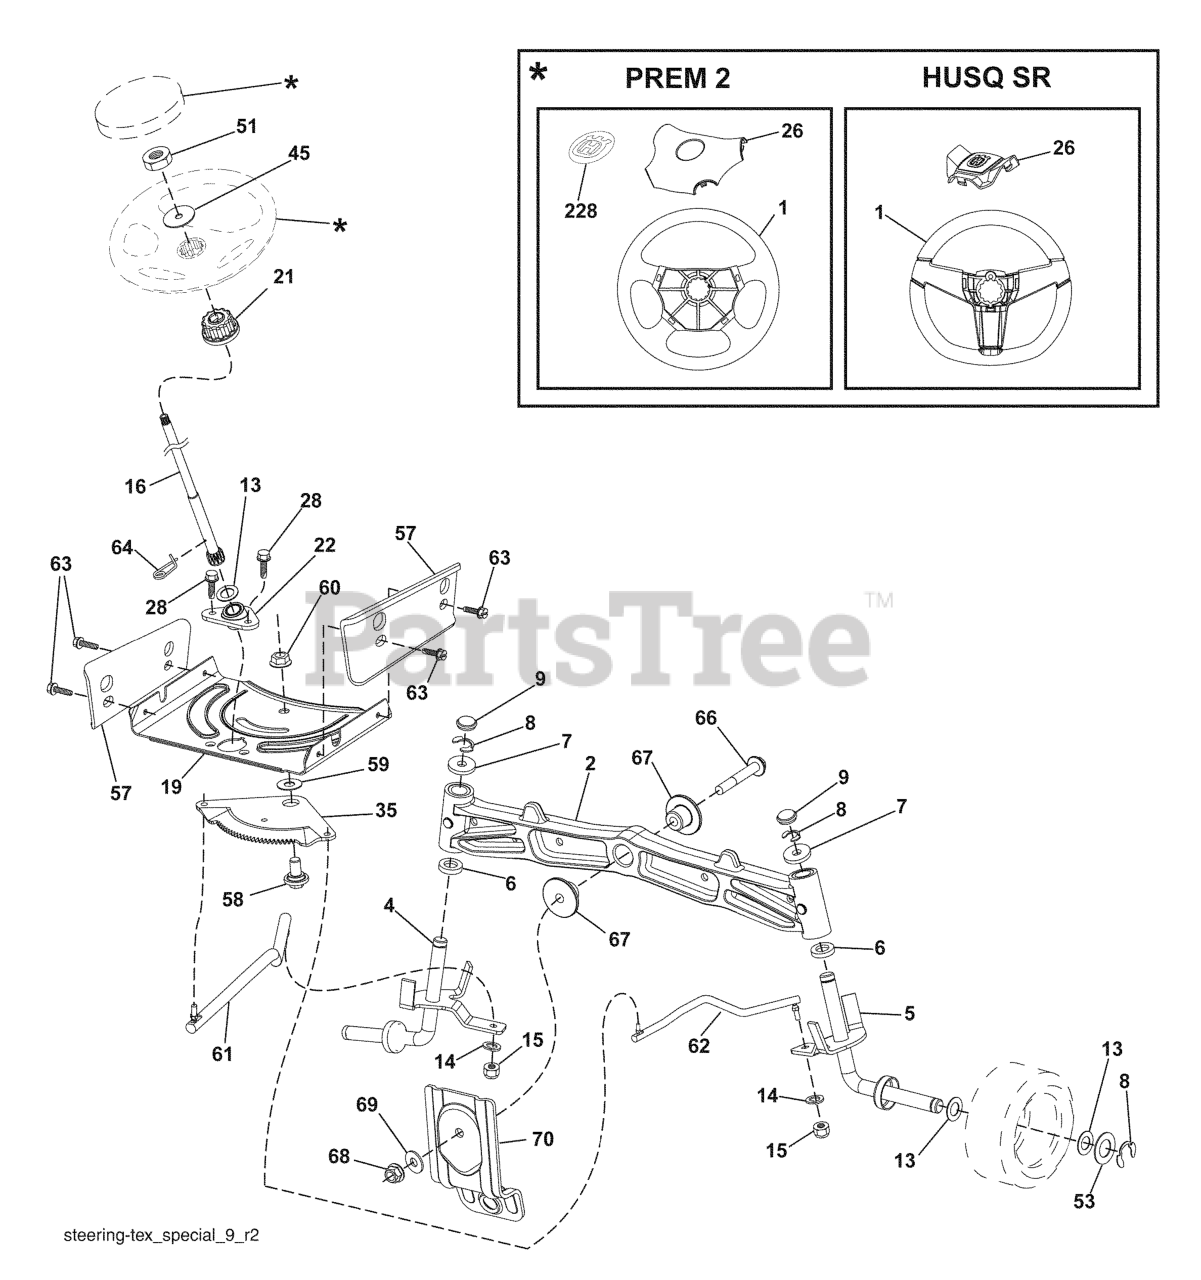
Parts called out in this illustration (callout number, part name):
1	RP WHEEL.STEER.HUSQ.PREM.OVMLD
2	AXLE.CAST.IRON
4	SPINDLE.WELDED.LH.15"TEX
5	SPINDLE.WELDED.RH.15"T
6	THRUST WASHER
9	CAP.SPINDLE.BLACK
14	WASHER, LOCK 3/8
15	NUT CROWNLOCK 3/8-24
16	SHAFT, STEERING
19	PLATE.STEER.DDL.NLT/NG
21	ADAPTER, WHEEL STNG..
22	BUSHING.ASM.STEERING.A
26	RP INSERT.CAP.WHL.STRG.HUSQ.
28	SCREW, 3/8-16X3/4
35	GEAR.SECTOR.PLATE.DDL.
45	WASHER 9/16"ID, 2 3/8"OD
51	NUT.HEX.1/2-20
53	WASHER.HARDENED
57	BRACKET.UPSTOP.TEX
58	BOLT.SHOULDER.SECTOR.P
59	WASHER.THURST.SECTOR.S
60	NUT FLANGE LOCK 5/8-11
61	DRAGLINK.LH.BALLSTUD.D
62	DRAGLINK.RH.BALLSTUD.D
63	SCREW
64	RETAINER.CLIP.SPRING.S
66	BOLT HEX FGHD 7/16-14 X 3 SERR
67	BUSHING.PM.FRONT AXLE
68	NUT.LOCK.FLANGE.7/16
69	WASHER.1.5X.505X.118
70	BRKT.DECK.SUSPENSION.F
228	DECAL.WHEEL.STRG.LGN.H
